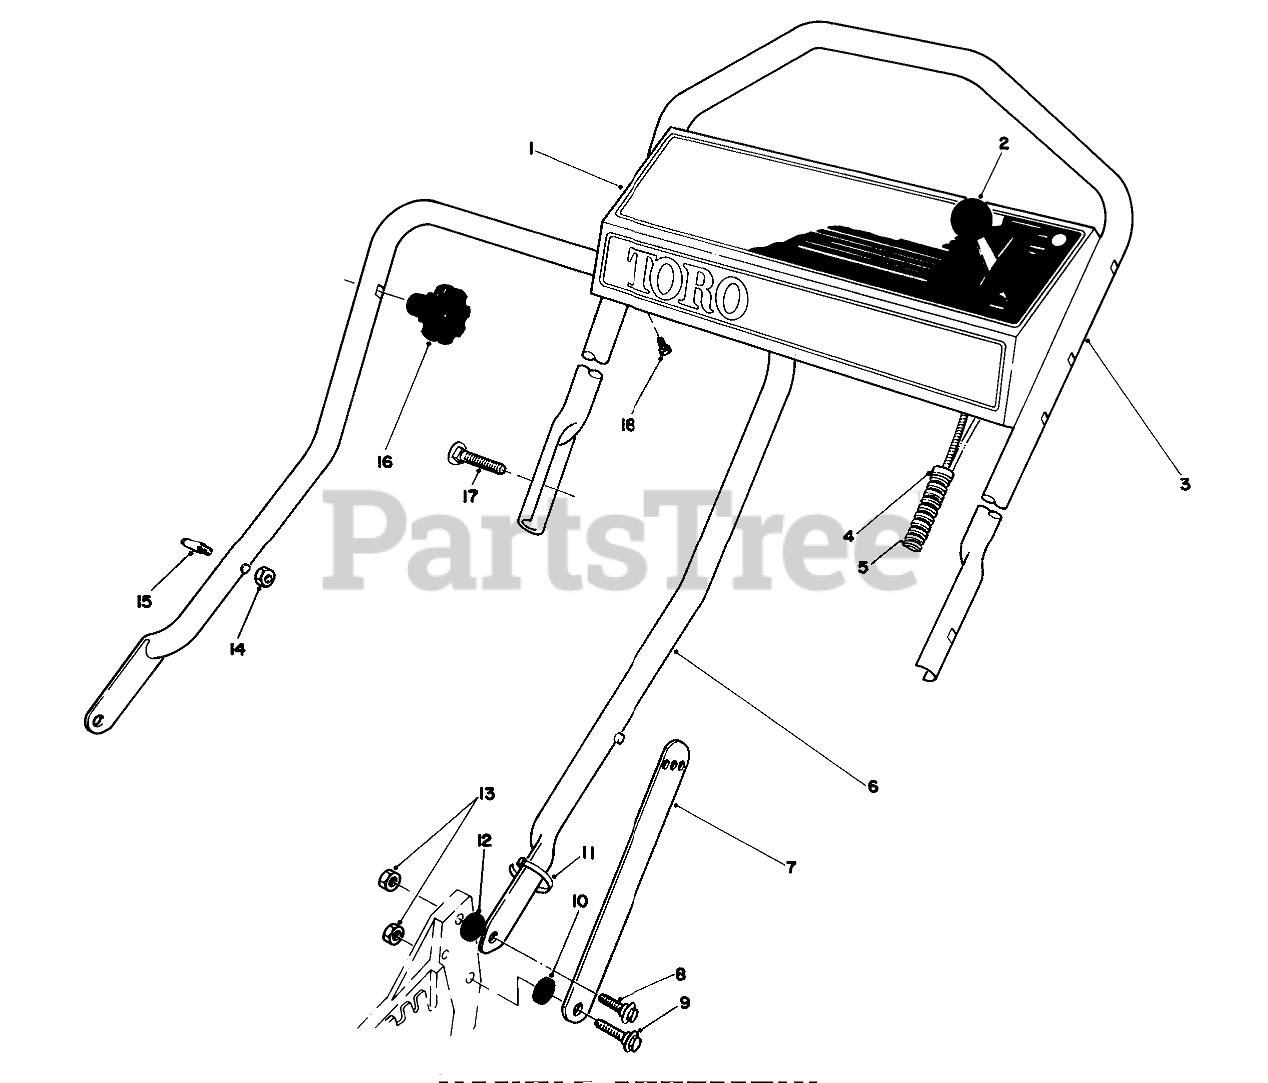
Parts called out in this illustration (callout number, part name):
1	Panel-Control
2	SERVICE THROTTLE CONTRO
3	Handle-Upper
4	FITTING-RING
5	CONTROL CABLE COVER
6	LOWER HANDLE ASM
7	Handle Latch
8	SCREW-SHOULDER
9	SCREW-SHOULDER
10	SPACER
11	TIE-CABLE
12	SPACER
13	NUT-LOCK, NI
14	NUT-LOCK, NI
15	HANDLE PIN
17	5/16-18 X 2 HNDLE SCREW
18	SCREW-HWHTF
